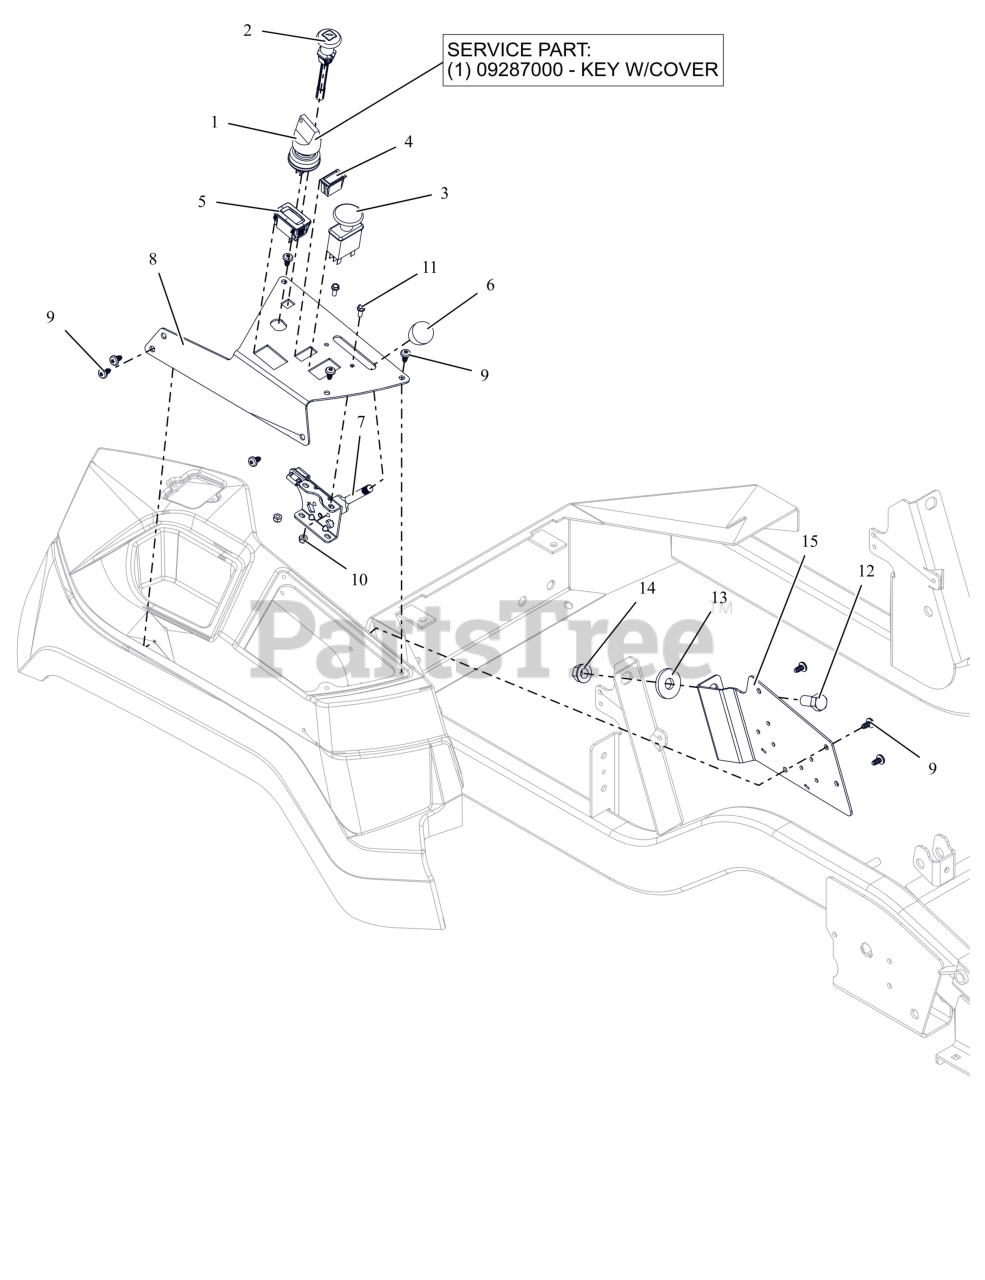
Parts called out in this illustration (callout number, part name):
1	SWITCH, IGNITION
1	KEY, W/ SHIELD
2	CABLE - CHOKE, SNAP-IN
3	SWITCH, CLUTCH
4	SWITCH,BLANK
5	HOUR METER
6	KNOB-CONTROL-BLACK .38-16X.50
7	CABLE, PRO THROTTLE CONTROL
8	PLATE, APEX CONTROL PANEL
9	SCR-PAN .25-15X.50 6L H/LZB500
10	NUT-LK-NYL #10-24 G2 ZCC
11	BLT, HWH #10-24X.50 ZCC
12	BLT, HEX .50-13X1.00 G5 ZCC
13	WSHR-FL-STL 0.562X1.5X0.187 ZCC
14	NUT-LK-CTR-FLG .500-13 GG ZCC
15	BRKT, FENDER/RELAY MOUNTING
